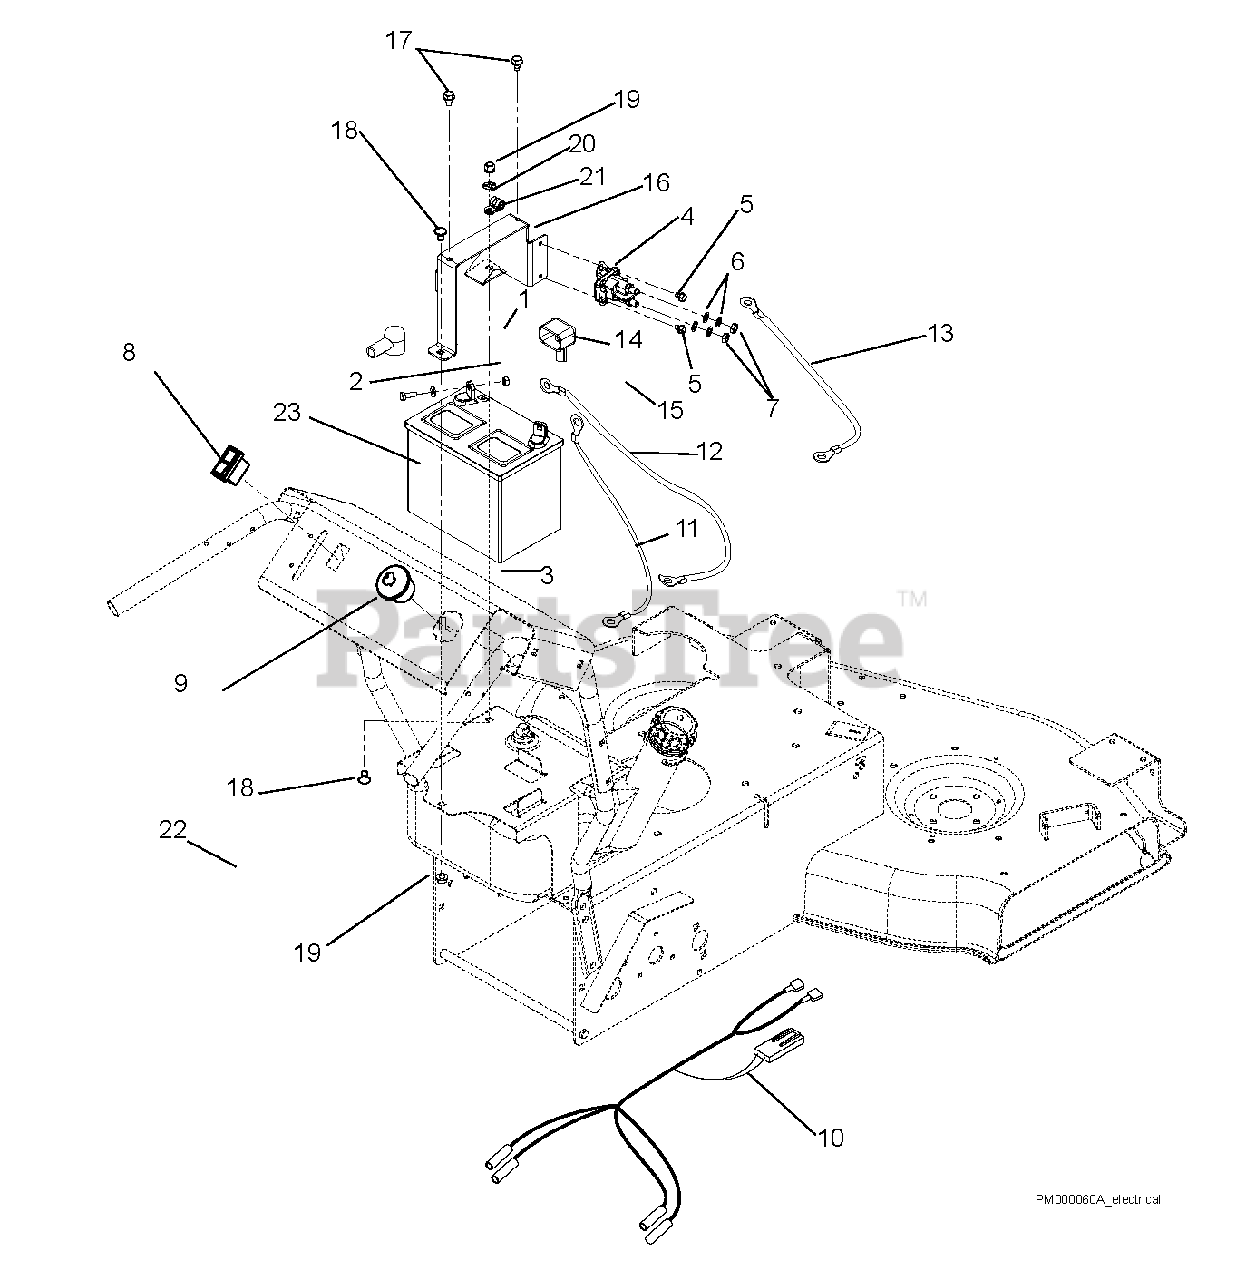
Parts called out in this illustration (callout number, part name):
1	Washer, Flat Steel .281 x .62 x .065
2	Bolt, Hex .25-20 x .75
3	Nut, KEPS .250-20
4	Solenoid
5	Screw, Tapping Hex Washer Head .250-20 x .37
6	Washer, Internal Lock .31
7	Nut, Jam .31-24
8	Switch, Rocker
9	KEYSWITCH-IGNITION 3 POS
9	Replacement Key
10	Harness, Wiring
11	Cable, Positive Battery 18.50"
12	Cable, Negative 26" 6 GA.
13	Cable, POS 6.75" Bent
14	Battery, Boot
15	Battery Boot
16	Bracket, Battery Mount
17	Screw, Tapping .31-18 x .50 Hex Washer Head
18	Bolt, Round Head Square Neck .31-18 x .50 Grade 5
19	Nut, Locking-Top-Flange .31-18
20	Nut, Push .312
21	Clamp, Cushioned Steel
22	Battery Mat
23	Battery, 12V 20HR;190CCA GEP (Can be replaced with U1 battery, see Owners Manual)
